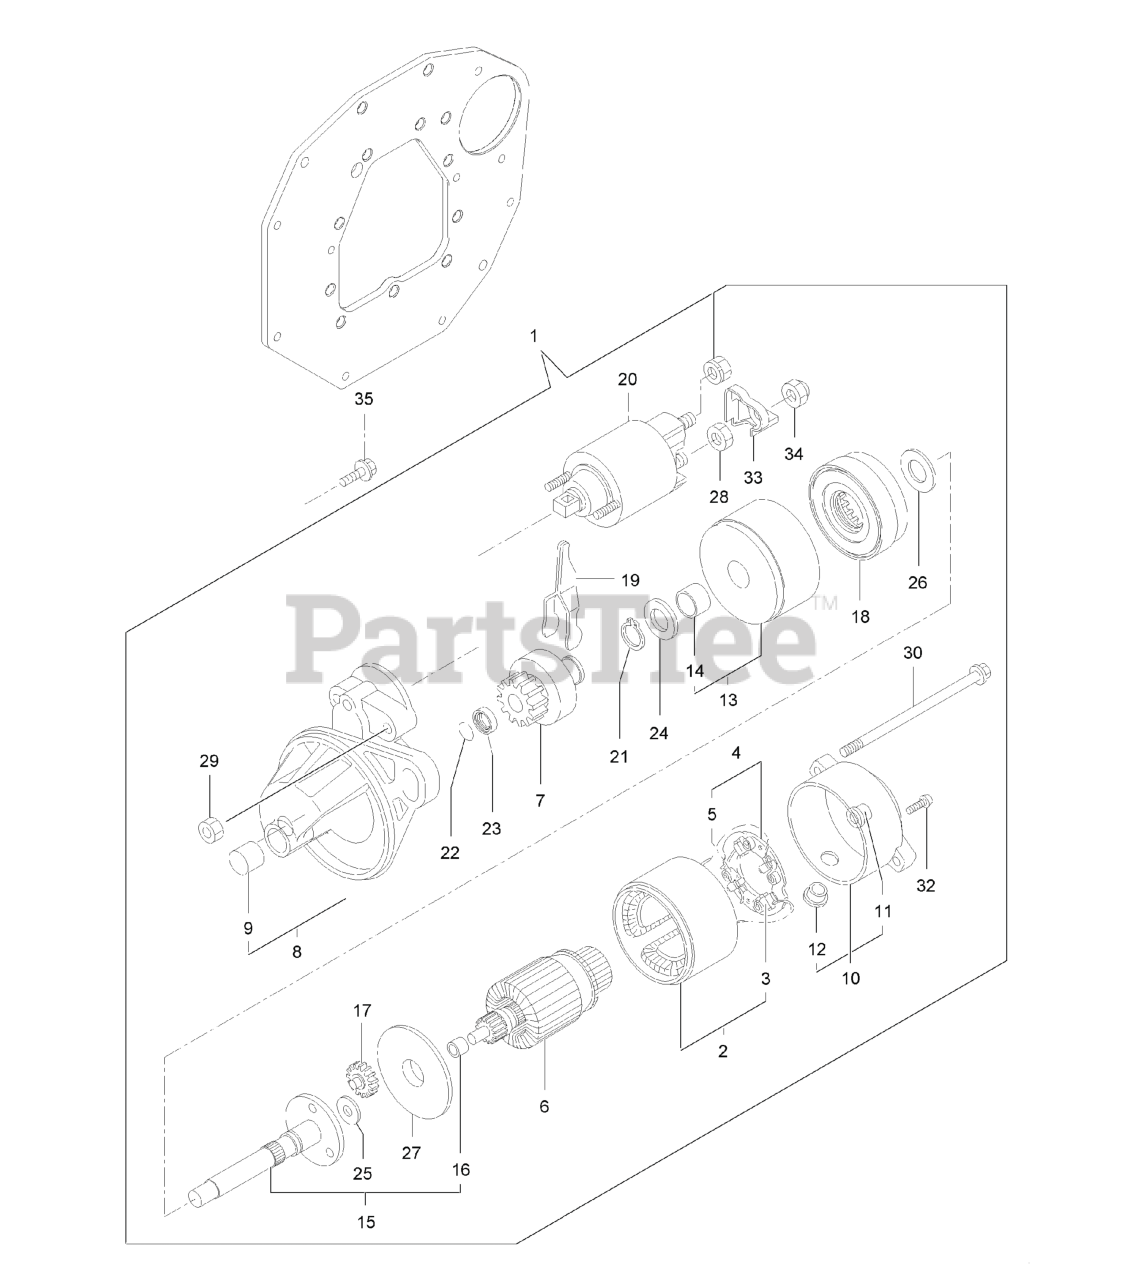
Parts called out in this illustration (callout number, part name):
1	STARTER ASM
2	YOKE ASM
3	STARTER KIT
4	HOLDER ASM
6	ARMATURE ASM
7	CLUTCH ASM
8	HOUSING ASM
9	BEARING, NEEDLE 1
10	FRAME ASM
11	BEARING
13	BEARING ASM
14	Bearing
15	SHAFT ASSY 1
16	Bearing
20	SWITCH ASM
30	BOLT-THROUGH
33	COVER-TERMINAL
